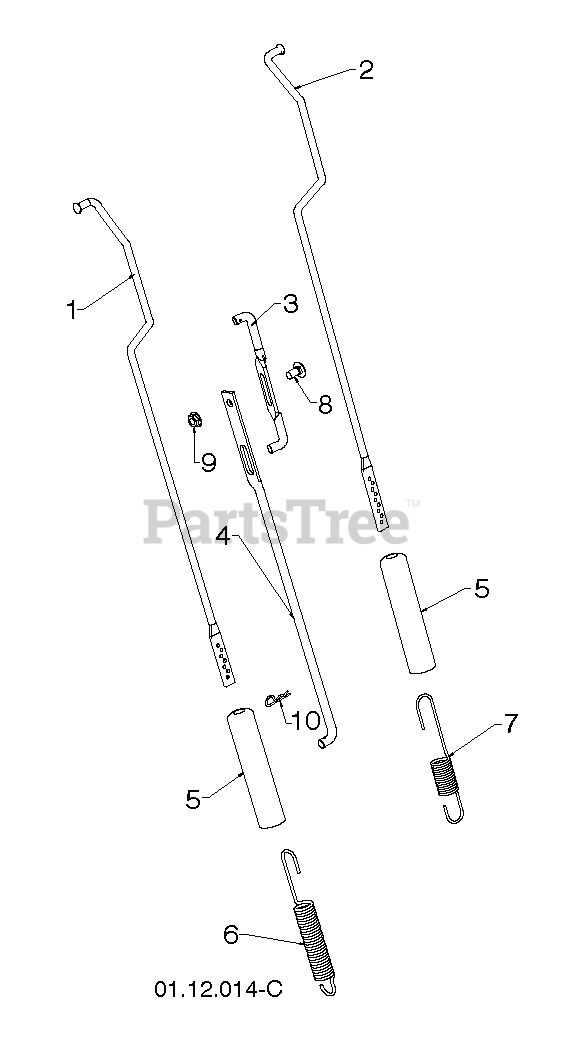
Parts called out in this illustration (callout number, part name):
1	ROD.IMPELLER
2	ROD.TRACTION
3	ROD.SHIFTER.TOP.HYD
4	ROD, LOWER, SPEED CONTROL
5	SLEEVE, SPRING
6	SPRING.CONTROL.ROD.SNOW
7	SPRING.TRACTION.ROD.SNOW
8	BOLT
9	NUT.FLANGE.5/16
10	SPRING RETAINER
